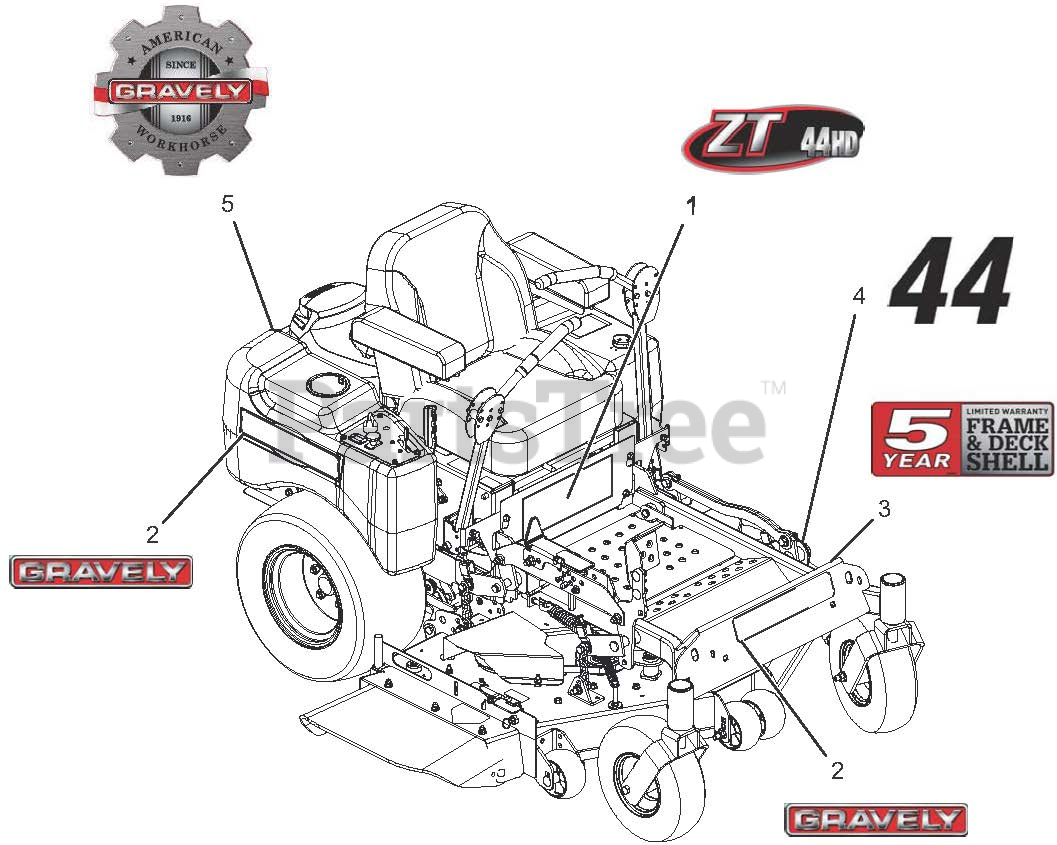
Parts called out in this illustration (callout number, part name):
1	DECAL, 44HD
2	DECAK, FUEL TANK - GRAVELY
3	DECAL, DECK WARRANTY - FAB GRAVELY
4	DECAL, 44"
5	DECAL, GRAVELY HERITAGE - SMALL
